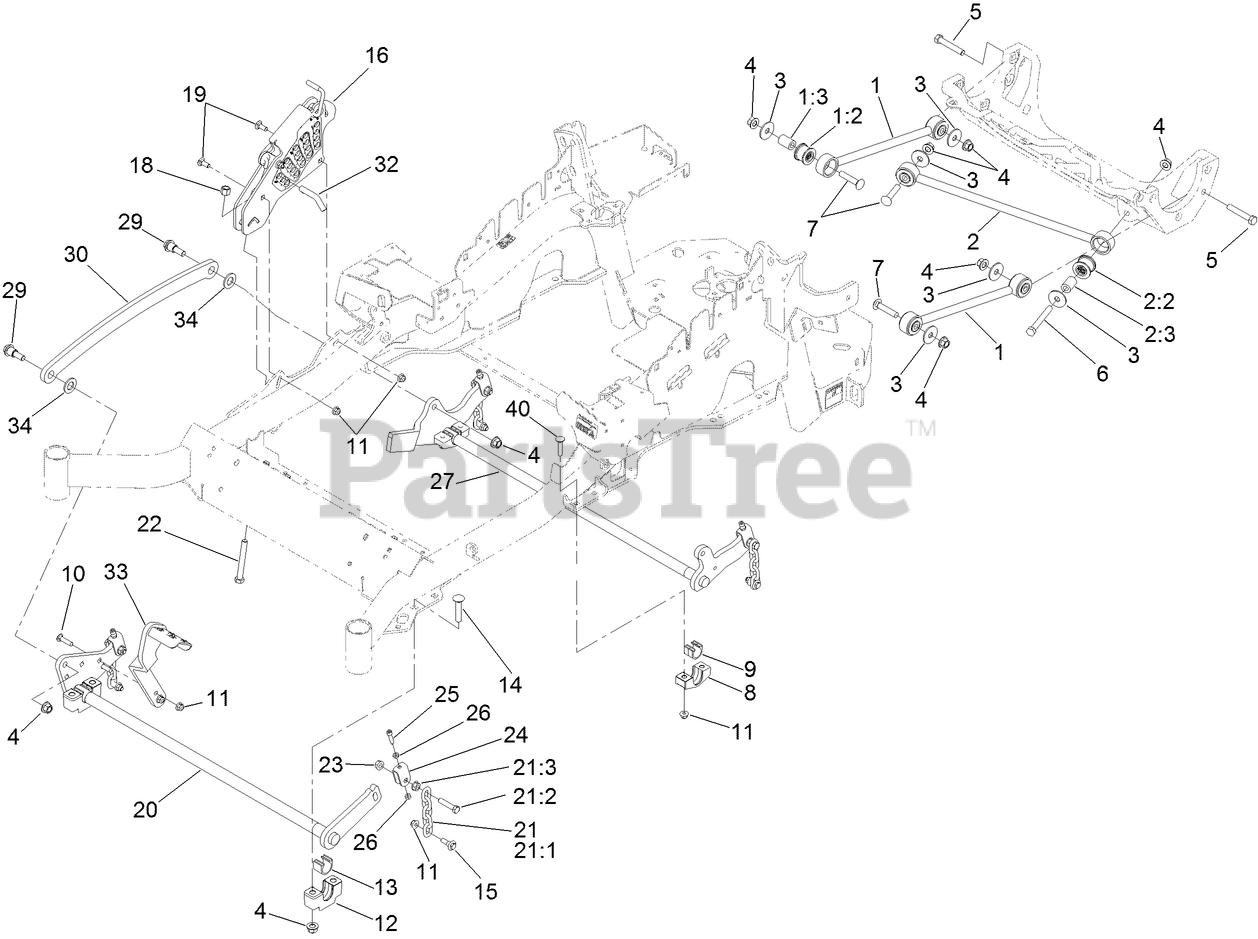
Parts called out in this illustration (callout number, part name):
1	DECK STRUT ASM
1:2	BUSHING-SUSPENSION, RUBBER
1:3	SPACER
2	PANHARD ROD ASM
2:2	BUSHING-SUSPENSION, RUBBER
2:3	SPACER
3	WASHER-THRUST
4	NUT-LOCK
5	SCREW-HH
6	SCREW-HH
7	SCREW-CARR
8	SUPPORT-CROSS SHAFT, REAR BEARING
9	BEARING-CROSS SHAFT, REAR
10	SCREW-CARR
11	NUT-HF, NI
12	SUPPORT-CROSS SHAFT, BEARING
13	BEARING-CROSS SHAFT, FRONT
14	BOLT-CARR
15	SCREW-SHOULDER, HHF
16	HEIGHT-OF-CUT ASM
18	NUT-LOCK, NI
19	BOLT-CARR
20	CROSS SHAFT-FRONT
21	DECK LIFT CHAIN ASM
21:1	CHAIN-LIFT, DECK
21:2	SCREW-HH
21:3	NUT-HF
22	BOLT-TAP
23	NUT-HF
24	YOKE-ADJUST, DECK
25	SCREW-HSH
26	NUT-JAM
27	LIFT-DECK, REAR
29	SCREW-SHOULDER, HHF
30	LINK-LIFT, DECK
32	PIN-HOC
33	FOOT LEVER
34	WASHER-FLAT
40	SCREW-CARR
